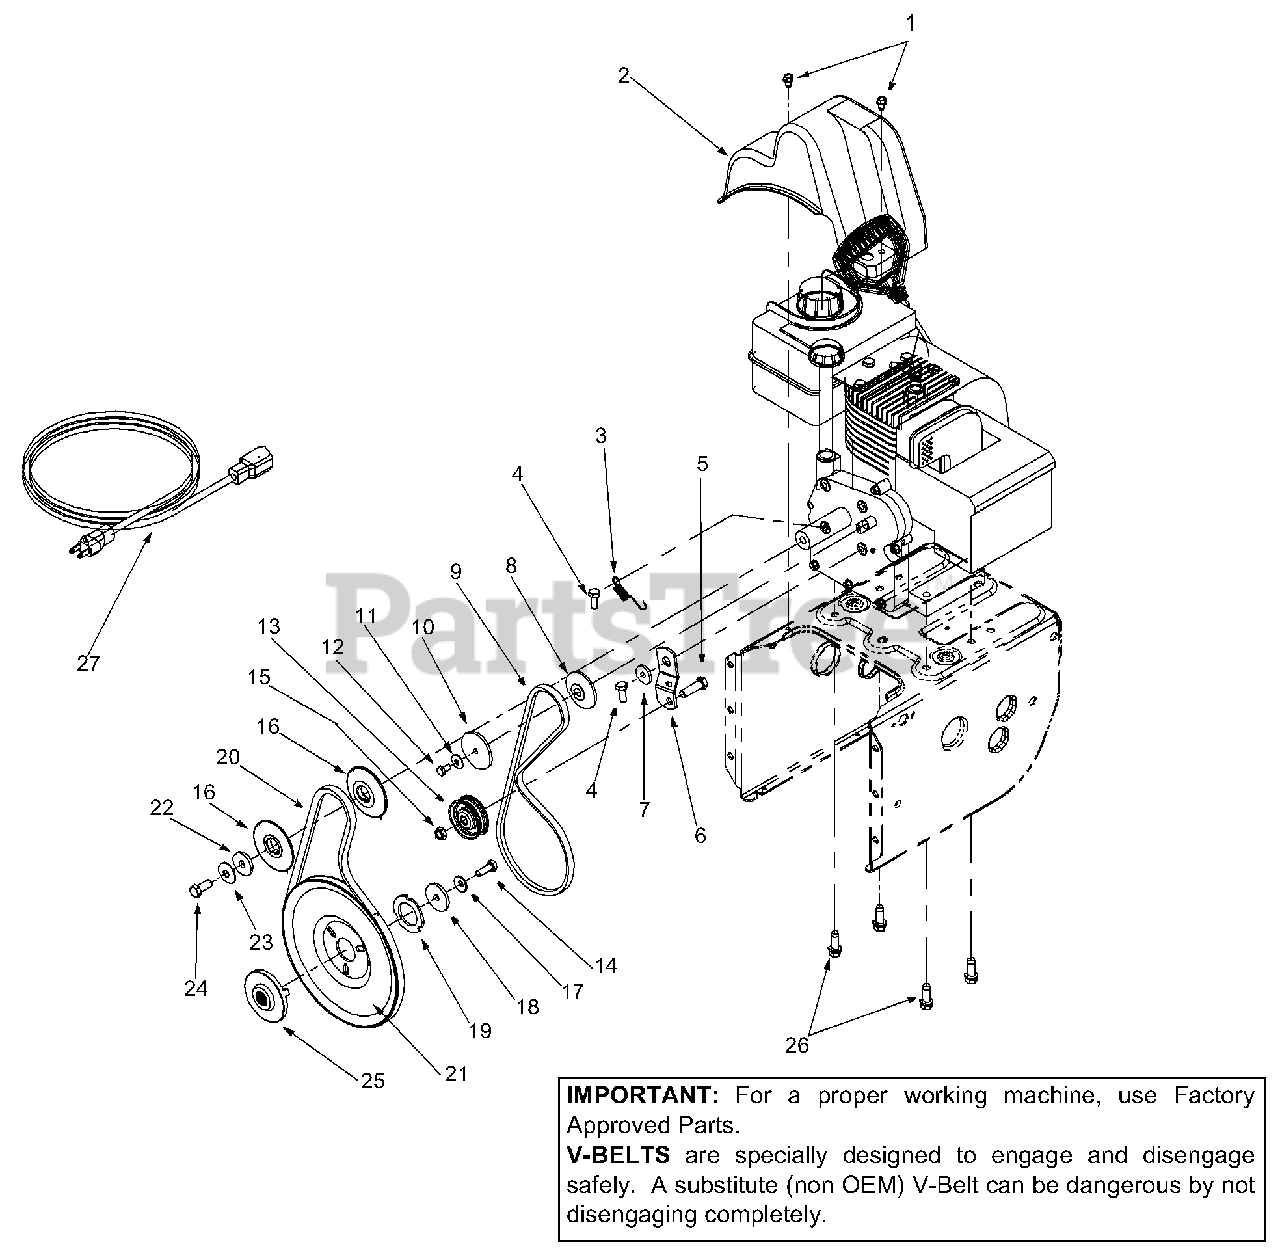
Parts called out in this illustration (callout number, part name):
1	Hex Washer Screw 1/4-20 x.5
2	Belt Cover
3	Extension Spring
4	Hex Screw 5/16-24 x .75
5	Hex Cap Screw 3/8-16 x 1.25
8	Pulley Half
9	V-Belt
10	Pulley Half
11	Bell Washer
12	Hex Cap Screw 1/4-28 x .50
13	Flat Idler
14	Lock Cap Screw 5/16-24
15	Lock Jam Nut 3/8-16
16	Pulley Half
17	Bell Washer
18	Flat Washer
19	Washer
20	Belt
21	Auger Pulley
22	Flat Washer
23	Bell Washer
24	Hex Cap Screw 3/8-24
25	Pulley
26	Hex Washer Screw 3/8-16 x 1.0
27	Extension Cord
